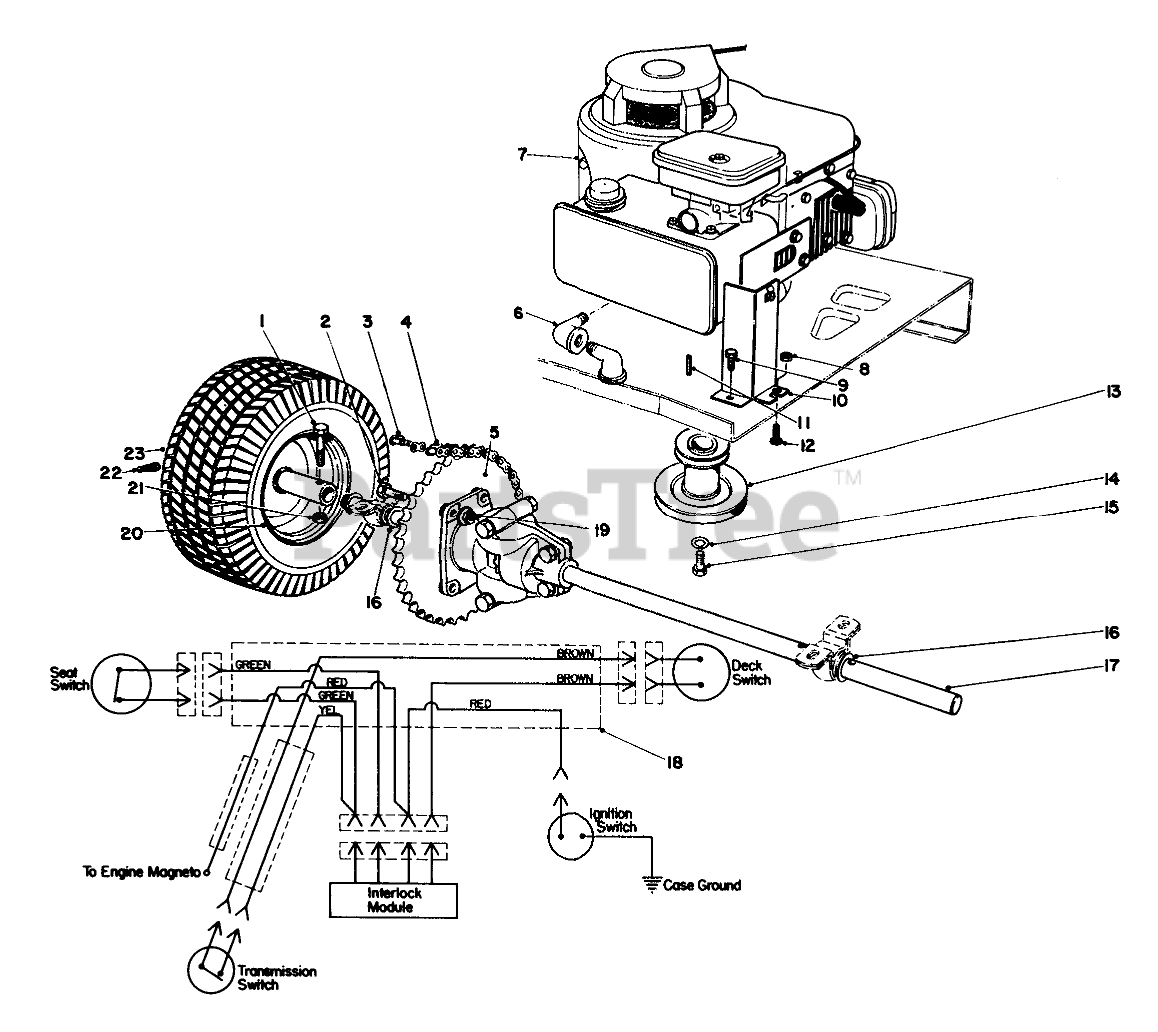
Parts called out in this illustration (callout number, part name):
1	SCREW-HH
2	SCREW-HH
3	LINK-CONNECTING
4	ROLLER CHAIN
5	Sprocket
6	90deg.Street Elbow
7	Engine
8	NUT-KEPS
9	SCREW-HWHTF
10	Support-Wire
12	5/16-18X5/8 TRS HD MS
13	ENGINE SHEAVE
14	WASHER-LOCK
15	SCREW-HH
16	WASHER
17	Differential
18	Wiring Harness
19	NUT-LOCK, CONE
21	NUT-LOCK, CONE
22	STEM-VALVE
23	Tire
